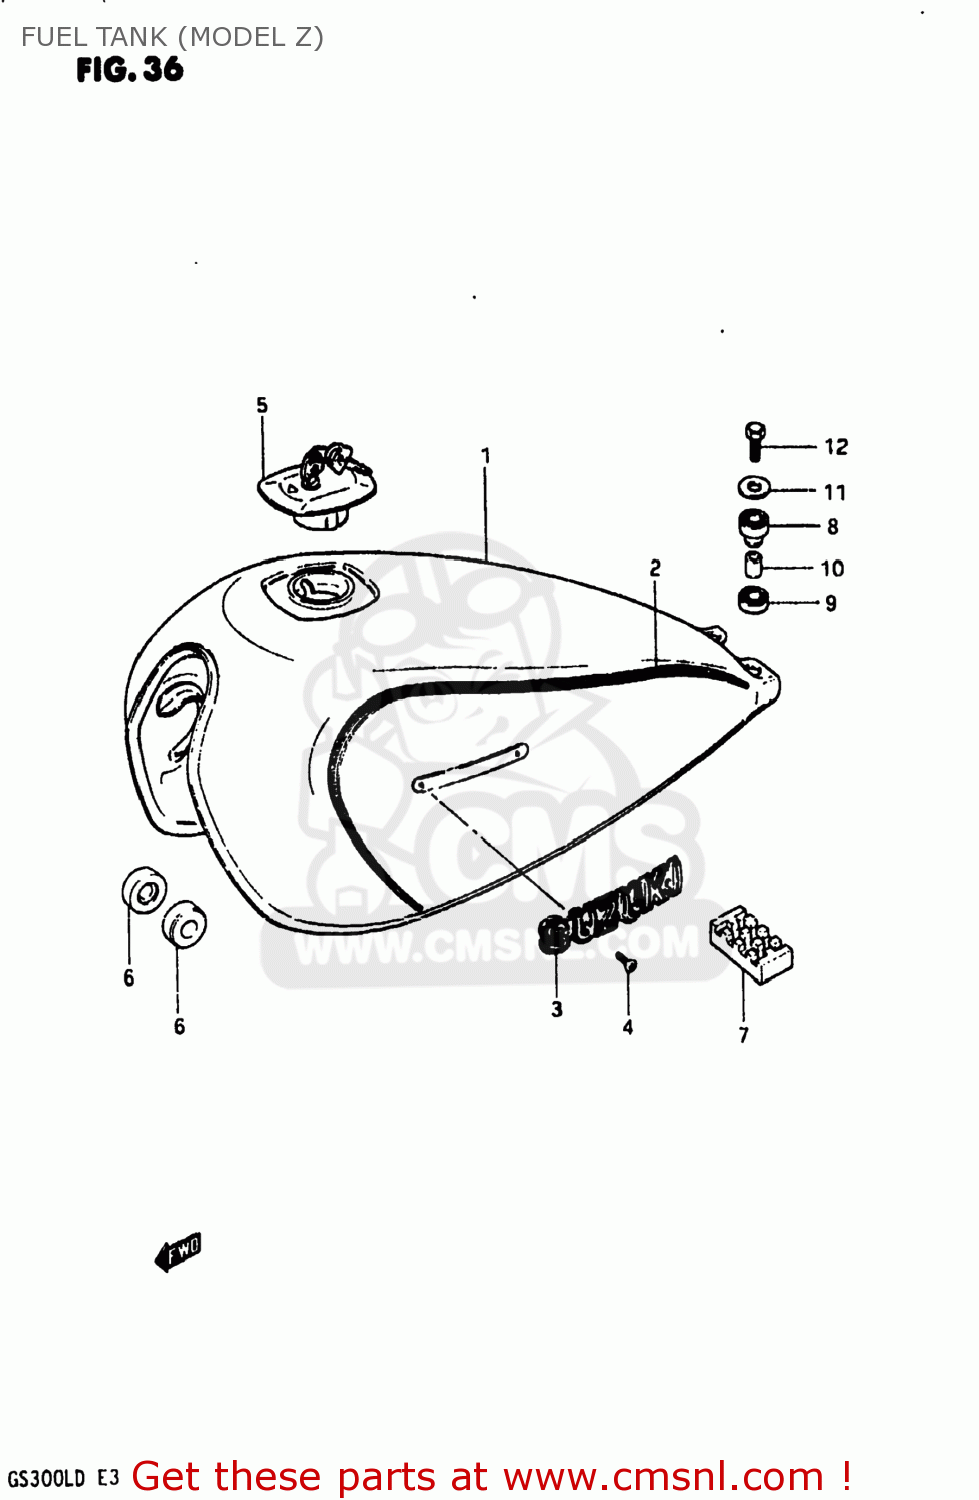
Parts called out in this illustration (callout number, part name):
1	TANK ASSEMBLY,FUEL
2	TAPE SET,FUEL TANK
3	EMBLEM,FUEL TANK
4	SCREW 3X6
5	CAP SET,FUEL TANK
6	CUSHION
7	CUSHION
8	CUSHION
9	CUSHION
10	SPACER
11	WASHER (6.5X24X1.6)
12	BOLT
